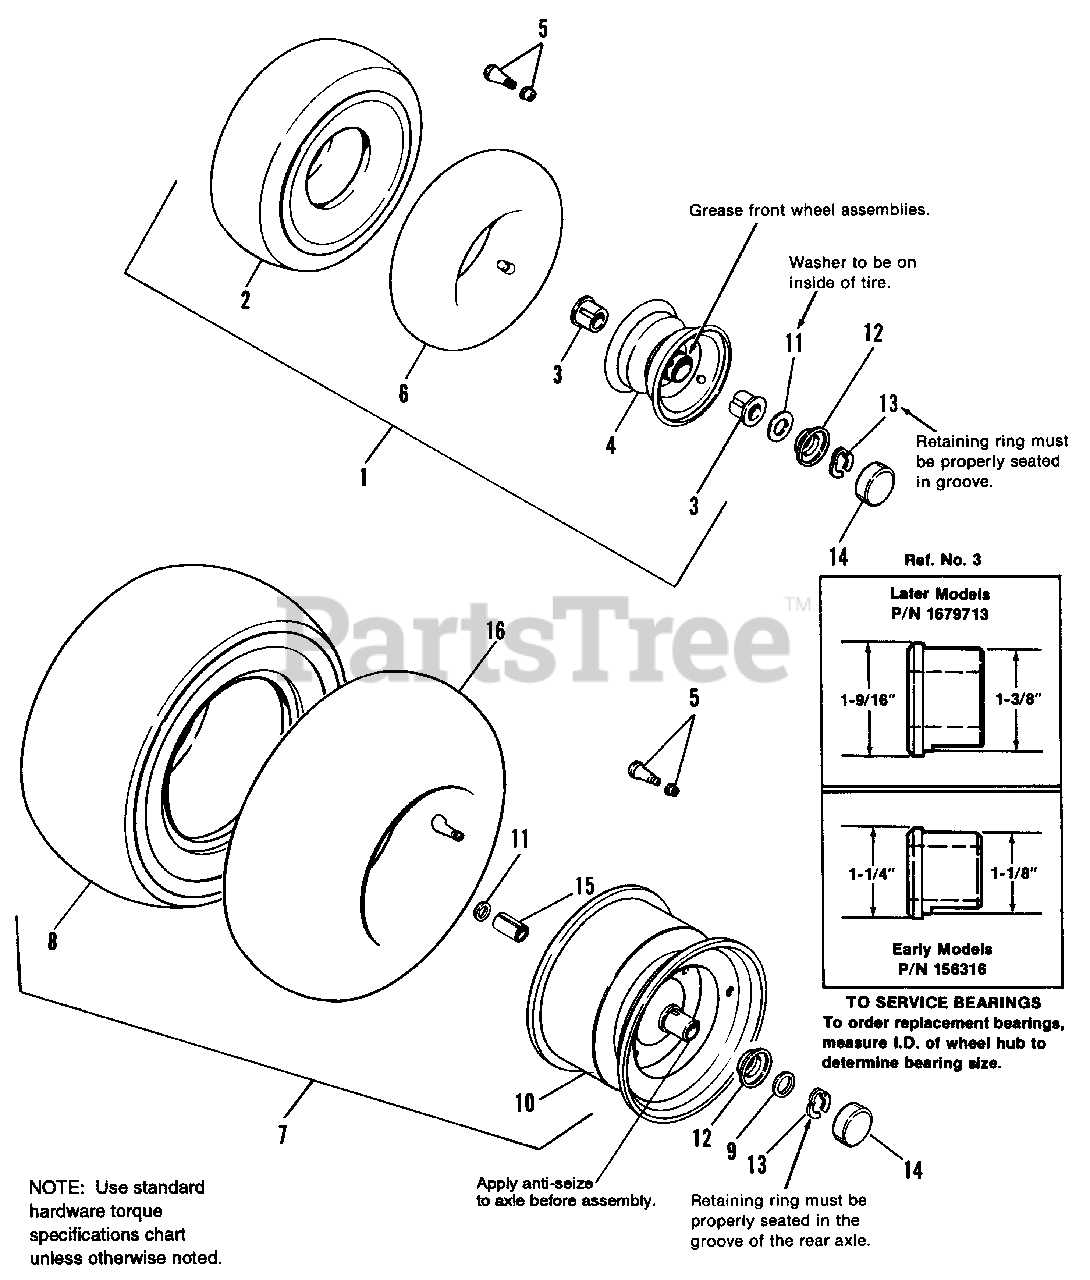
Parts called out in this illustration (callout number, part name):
1	WHEEL & TIRE ASSY. (15 x 6.00-6), Beige (Incl. Ref. Nos. 2, 3, 4, 5, & 6)
1	WHEEL & TIRE ASSY. (15 x 6.00-6), Silver (Incl. Ref. Nos. 2, 3, 4, 5, & 6)
2	TIRE (15 x 6.00-6)
3	BEARING, 1-9/16" Outside O.D, 1-3/8"BEARING, 1-9/16l Wheel Assembly. See inset illustration on page 42.)
3	BEARING, 1-1/4" Outside O.D, 1-1/8"BEARING, 1-1/4 Wheel Assembly. See inset illustration on page 42.)
4	WHEEL ASSY. (Incl. Ref. No. 3), Beige
4	WHEEL ASSY., Silver
5	VALVE STEM & CAP
6	TUBE (4.10/3.50-6) Service Only.
7	WHEEL & TIRE ASSY. (18 x 8.50-8), Beige (Incl. Ref. Nos. 5, 8 & 10)
7	WHEEL & TIRE ASSY. (18 x 8.50-8), Silver (Incl. Ref. Nos. 5, 8 & 10)
8	TIRE (18 x 8.50-8)
9	WASHER (Rear Axle)
10	WHEEL ASSY., Beige
10	WHEEL ASSY., Silver
12	RETAINER, Hubcap
15	SPACER, Axle
16	TUBE (18 x 8.5-8)
